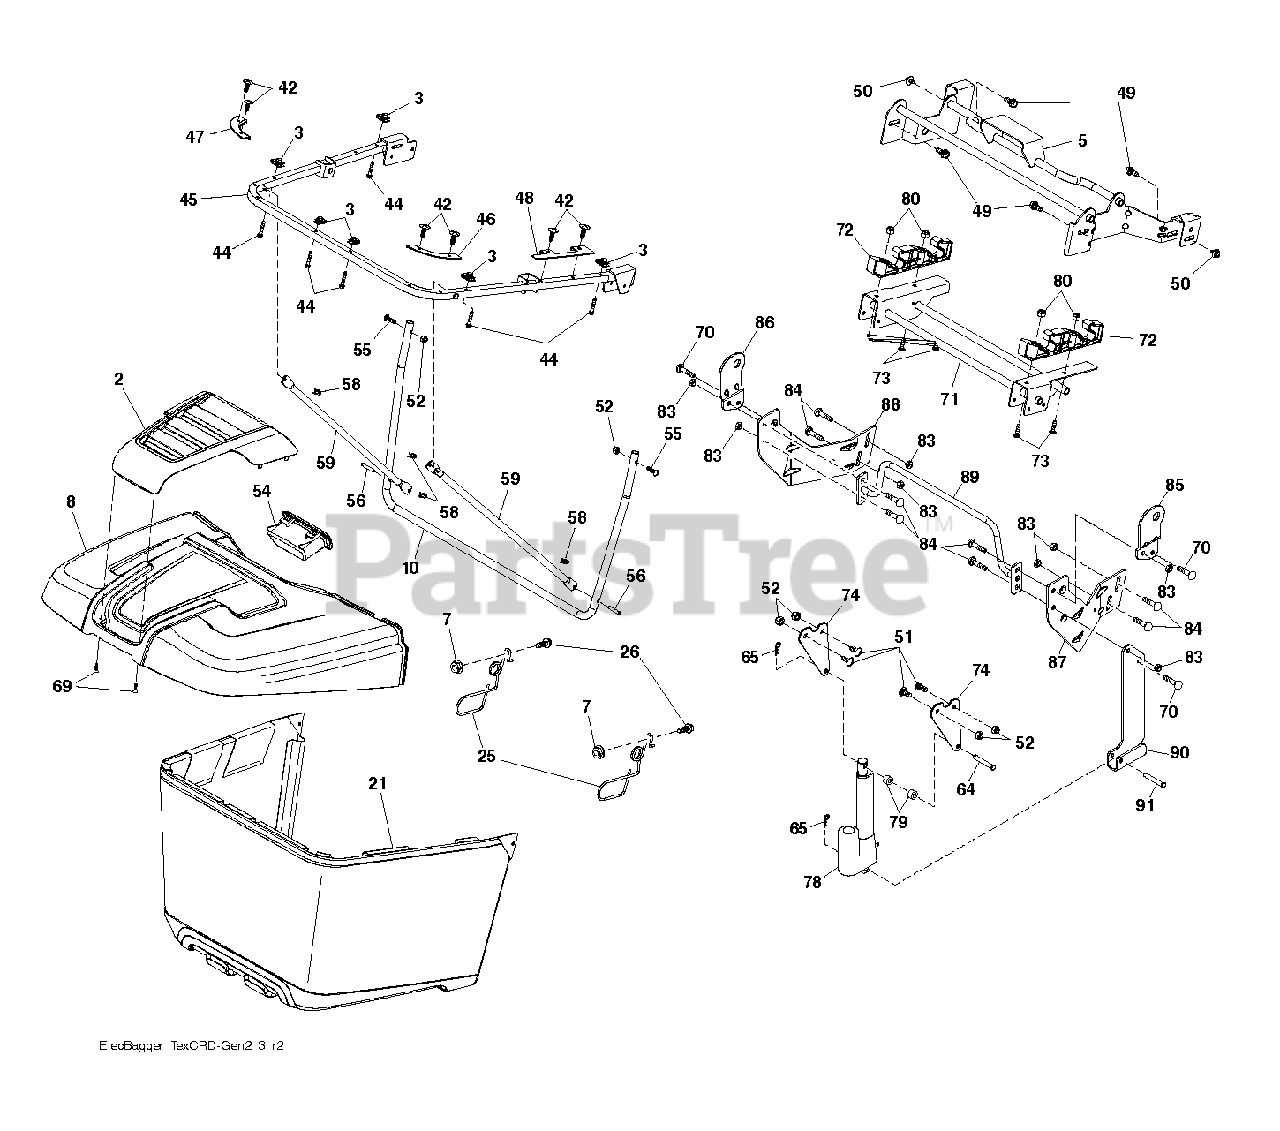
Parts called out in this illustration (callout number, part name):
2	APPLIQUE.BAGGER
3	1/4-20 U NUT
7	NUT T
10	FRAME TEX_CRD_GEN2 BAGGER FRAM
21	BAG FRAME BAGGER ASSEMBLY. HUS
25	LATCH LATCH. BAG. CRD GEN 2
26	SCREW HEX CRT
42	CLIP CHRISTMAS TREE CLIP
45	FRAME TEX_CRD_GEN2 UPPER U FRA
46	CONNECTOR RIGHT BAGGER CORNER
47	CONNECTOR LEFT BAGGER CORNER C
48	BAFFLE BAGGER SIDE CLOSE-OUT
49	BOLT, SHOULDER 5/16-18
50	BOLT, 5/16-18 X 1 3/4
51	BOLT.CARR.SQNK.5/16-18UNC.X3/4
52	NUT.71038.31-18.HEX.NYLOCK
54	HANDLE BAGGER TOP FRONT HANDLE
55	BOLT
56	PIN.CLEVIS.183
58	RETAINER CLIP PM
59	TUBE BAGGER SPREADER TUBE, TEX
65	RETAINER M
69	SCREW,#8.FLAT.HEAD.DRILL.TIP
70	SCREW, 3/8-16X3/4
73	BOLT.CARRIAGE.5/16-18
79	SPACER.NYLON.75" X .4375
80	NUT LOCK HEX FLANGE 5/16-18
83	NUT
84	BOLT D
85	BRACKET.RH.PIVOT.ELE.DUMPX431
86	BRACKET.LH.PIVOT.ELE.DUMPX431
87	BRACKET.RH.MID.SUP.BAG.TEX.CRD
88	BRACKET.LH.MID.SUP.BAG.TEX.CRD
89	TUBE.WELD.OFSET.STRUT.BAG.X431
90	BRACKET.ELE.DUMP.ACT.BAG.X431
91	PIN.CLEVIS.(.375 X 1.25)
